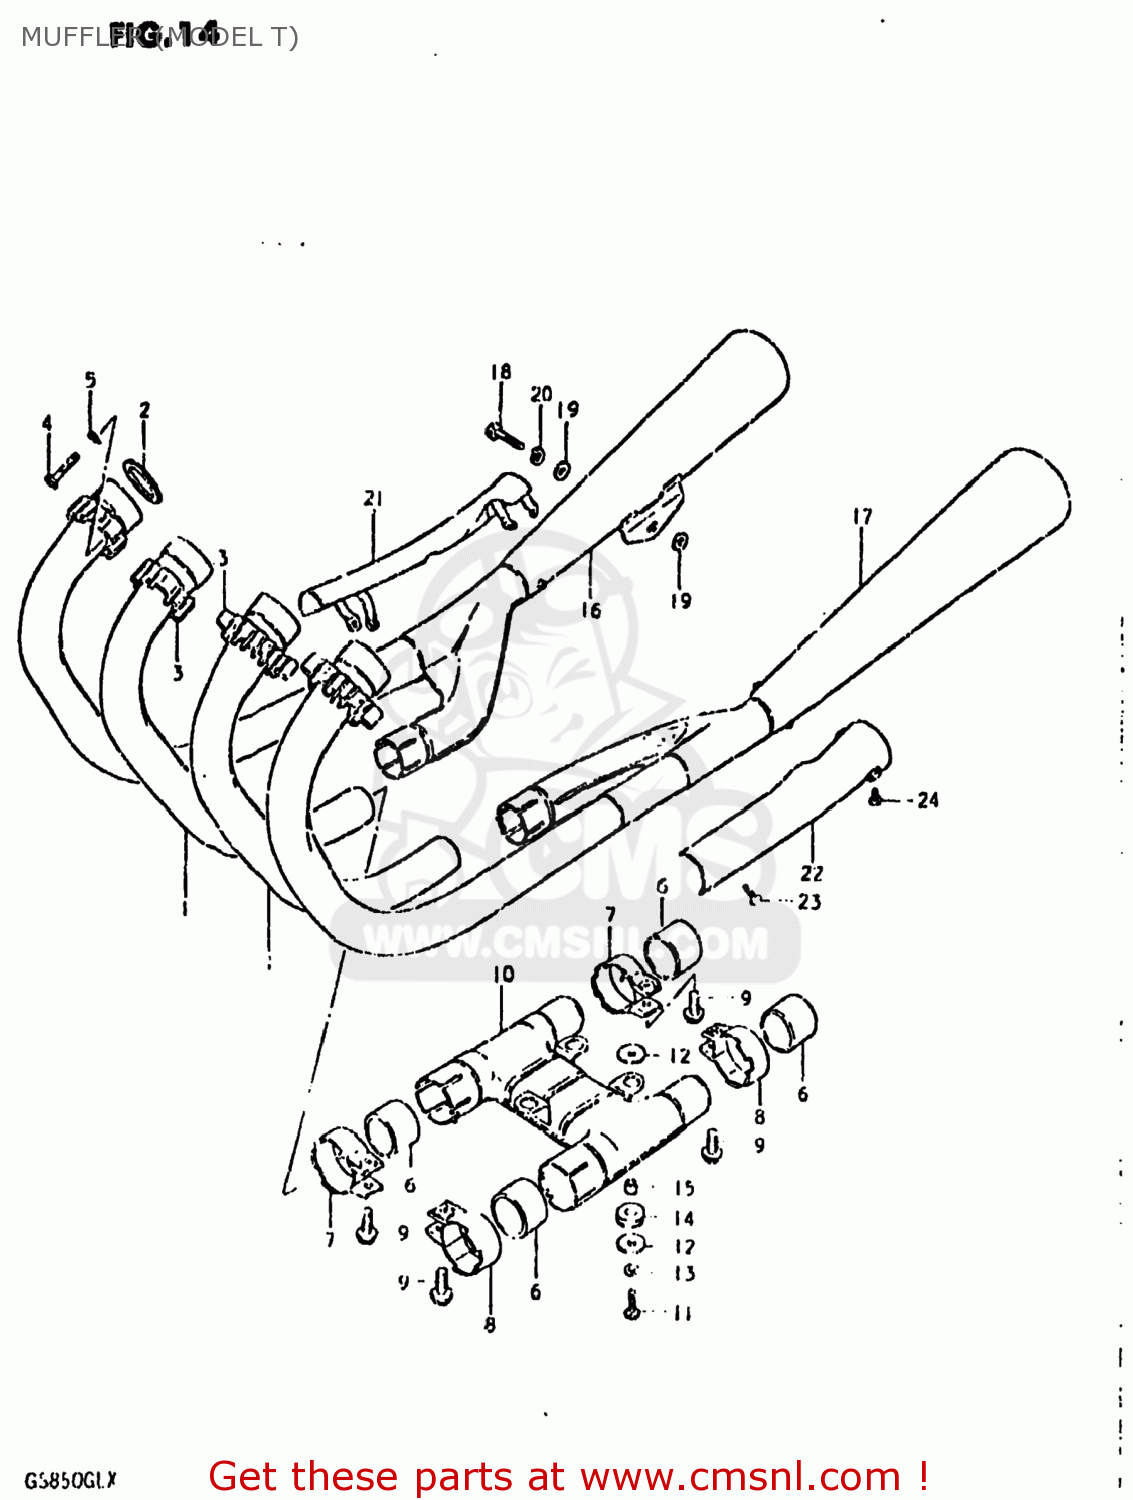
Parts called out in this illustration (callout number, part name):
1	PIPE,CENTER EXHAUST
2	GASKET,EXHAUST PIPE (NAS)
3	CLAMP,EXHAUST PIPE
4	BOLT
5	LOCK WASHER
6	CONNECTOR,MUFFLER
7	CLAMP,MUFFLER CONNECTOR,R
8	CLAMP,MUFFLER CONNECTOR,R
9	BOLT
10	BODY,PREMUFFLER
11	BOLT
12	WASHER
13	LOCK WASHER
14	CUSHION
15	SPACER(6.5X10.5X6.5)
16	BODY,MUFFLER
17	BODY,MUFFLER
18	BOLT 10X30
19	WASHER
20	LOCK WASHER
21	COVER,MUFFLER
22	COVER,MUFFLER
23	SCREW
24	SCREW
